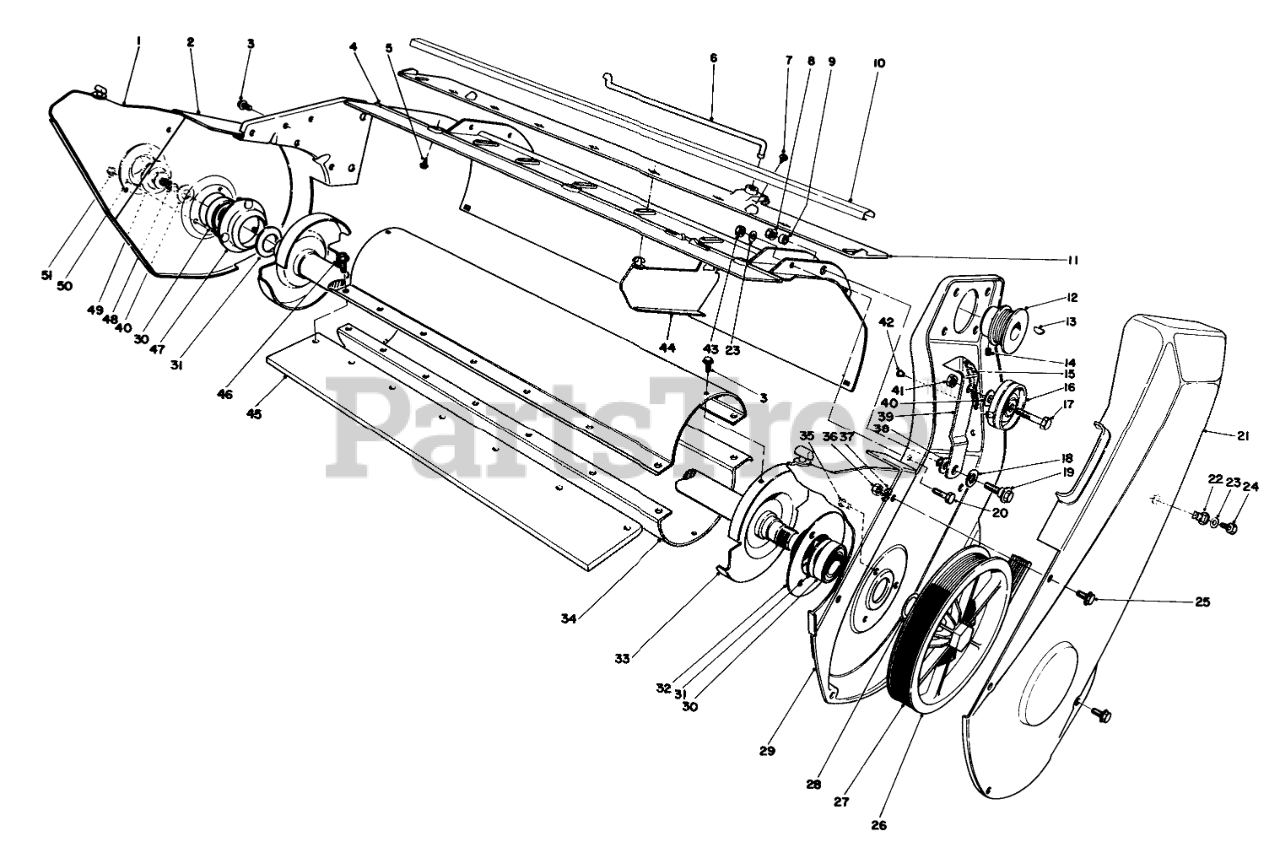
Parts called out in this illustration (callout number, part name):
1	OUTSIDE VANE
2	Plate-R.H. Side
3	SCREW-HWH
4	HOUSING ASSEMBLY
5	SCREW-THREAD FORMING
6	VANE ADJ LINKAGE
7	SCREW-HWHTF
8	NUT-HF
9	SPACER
10	Moulding
11	Mount-Vane
12	Pulley
13	KEY-WOODRUFF
14	SCREW-HSH
15	IDLER SPRING
16	IDLER PULLEY
17	SCREW-HH
18	WASHER
19	SCREW-SHOULDER
20	SCREW-HH
21	Cover-Drive
22	PLASTIC GROMMET
23	WASHER-FLAT
24	SCREW-HWH
25	SCREW-SHWH
26	PULLEY ASM ROTOR
27	BELT - DRIVE
28	WASHER
29	Plate-L.H. Side
30	BEARING-BALL
31	WASHER-THRUST
32	FLANGE-BEARING
33	END CAP WA
34	Shell-Rotor
35	RIVET
36	NUT-LOCK, NI
37	WASHER-FLAT
38	WASHER-PIVOT
39	IDLER ARM
40	WASHER-FLAT
41	NUT-LOCK, NI
42	Eyelet
43	NUT-LOCK, CONE
44	CENTER VANE
45	ROTOR BLADE
46	Screw
47	FLANGE-BEARING
48	SCREW-HHF
49	WASHER-RUBBER
50	Trough
51	NUT-CAP
